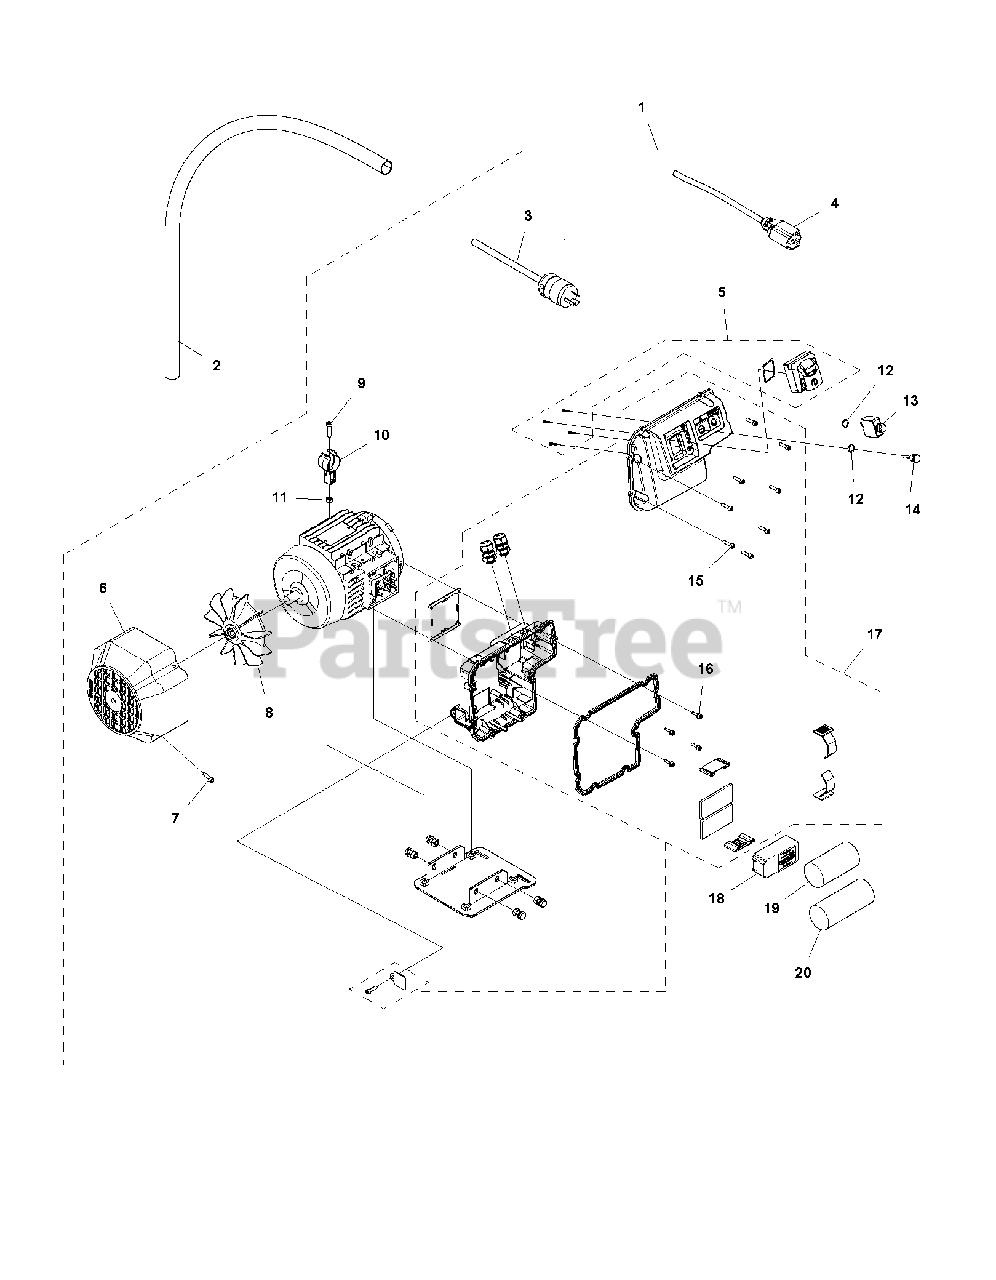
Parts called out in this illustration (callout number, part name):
9	SCREW IHSCM
11	HEXAGON LOCKING NUT
15	SCREW IHSCM
